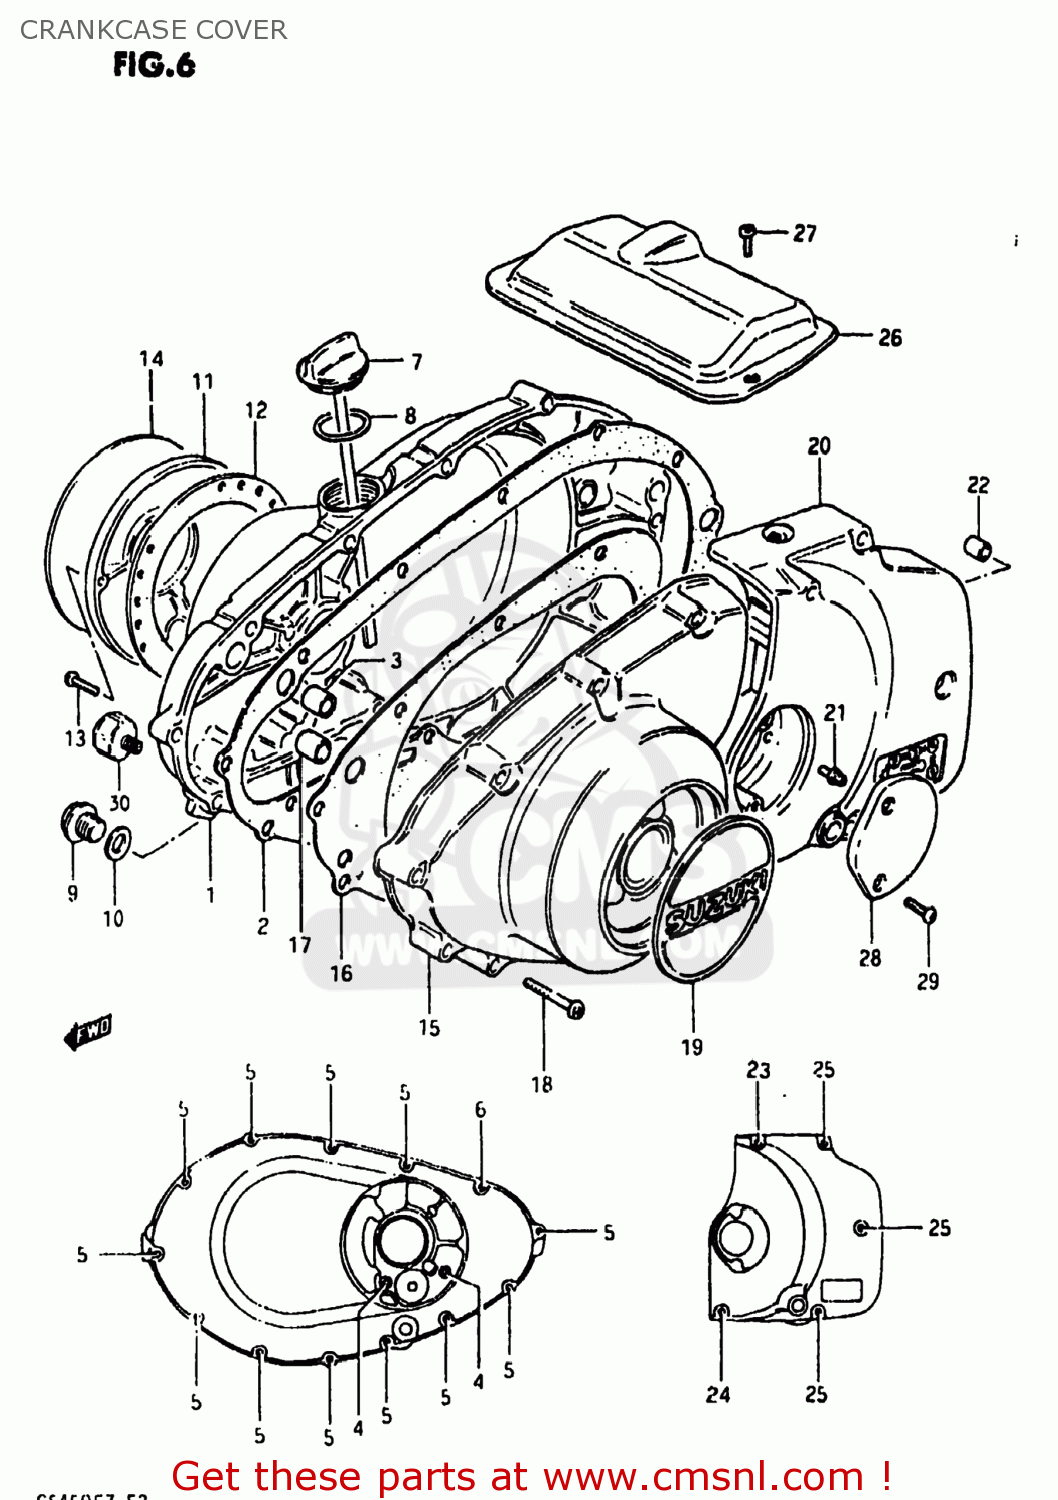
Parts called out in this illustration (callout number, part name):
1	COVER,CLUTCH
2	GASKET,CLUTCH COVER (MCA)
3	PIN
4	SCREW
5	BOLT (6X35)
6	BOLT
7	GAUGE,OIL LEVEL
8	O-RING
9	PLUG (14X12)
10	GASKET(14X19.2X2) (NAS)
11	COVER,CONTACT BREAKER
12	GASKET,CONTACT BREAKER COVER (NAS)
13	SCREW
14	EMBLEM,MAGNETO COVER
15	COVER
16	GASKET,MAGNETO COVER (MCA)
17	PIN
18	BOLT (6X35)
19	EMBLEM,MAGNETO COVER
20	COVER,SPROCKET
21	NIPPLE
22	PIN
23	SCREW 6X65
24	SCREW
25	SCREW
26	COVER,STARTER MOTOR
27	SCREW
28	CAP,CLUTCH RELEASE ADJUST
29	SCREW 5X12
30	SWITCH ASSEMBLY
